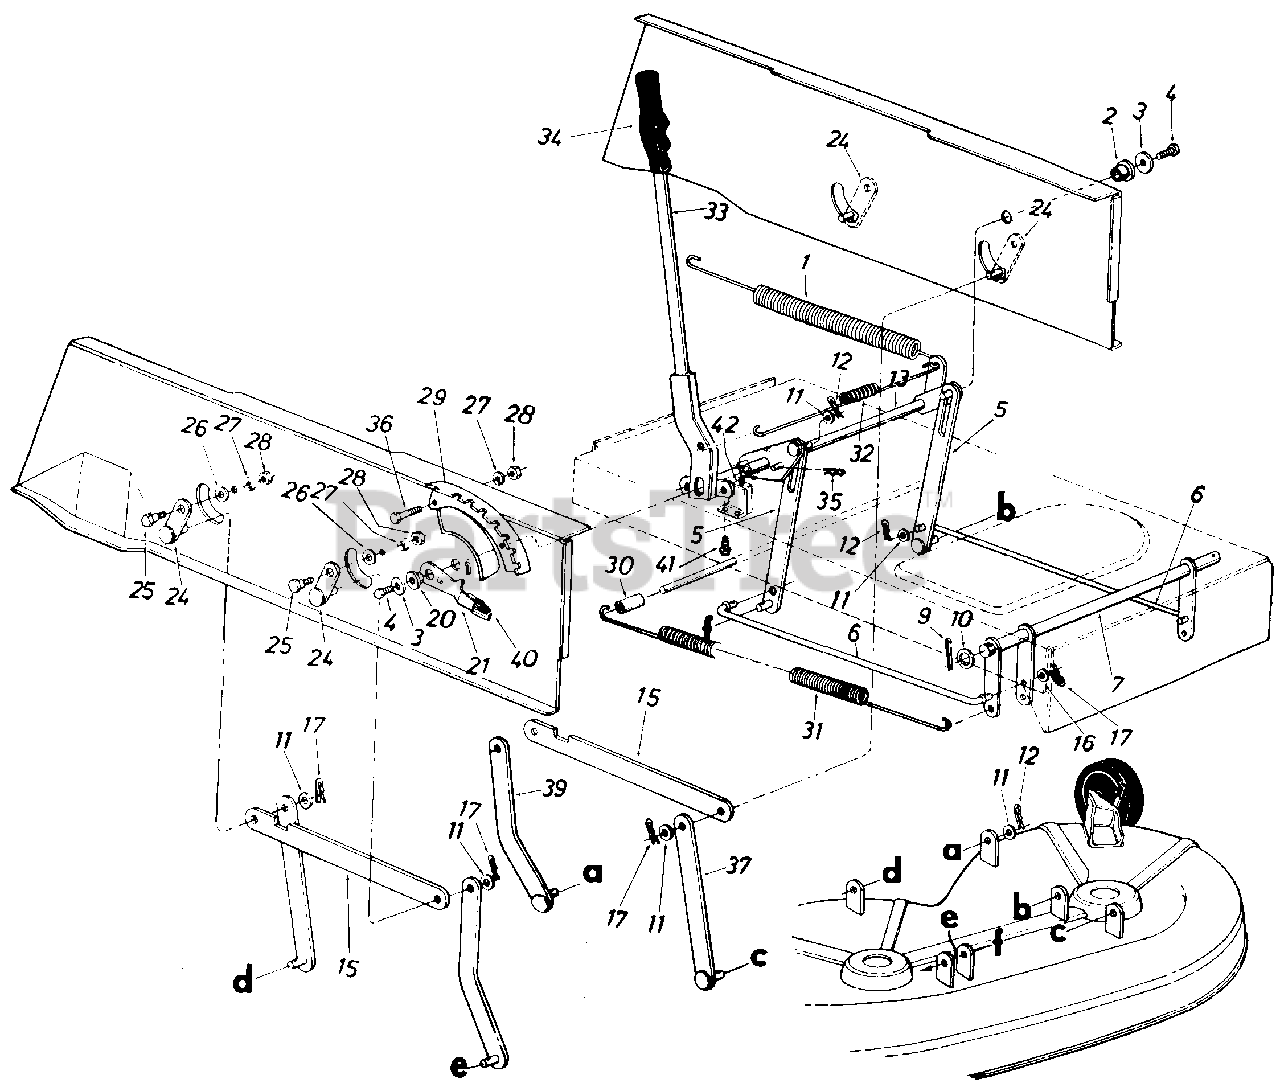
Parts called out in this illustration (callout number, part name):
1	Extension Spring .99" O.D. x 11.00" Lg.
2	Flange Bearing .634" I.D.
3	Fl-Wash. .344" I.D. x 1.125"
4	Hex Wash. Hd. 5/16-18 x .62" Lg.
5	Link Deck Lift Ass'y.
6	Stabilizer Rod
7	Stabilizer Shaft Ass'y.
9	Cotter Pin 1/8" Dia. x 1-1/4"*
10	Fl-Wash. .635" I.D. x 1.12"
11	Fl-Wash. .531" I.D. x .940"
12	Inter. Cotter Pin
13	Lift Shaft Ass'y.
15	Connecting Rod
16	Fl-Wash. .40" I.D. x .88"
17	Inter. Cotter Pin-3/8" Rod
20	Flange Brg. .630" I.D.
21	Deck Lift-Down Stop
24	Pivot Link Ass'y.
25	Shld. Bolt .437" Dia. x .180" Lg. (5/16-18)
26	Fl-Wash. .344" I.D. x .62"
27	L-Wash. 5/16" I.D.
28	Hex Nut 5/16-18 Thd.
29	Index Brkt.
30	Spacer .523" I.D. x .640" O.D. x 1.95" Lg.
31	Ext. Spring .99" O.D. x 1 3.25" Lg.
32	Ext. Spring .56" O.D. x 32 0 Coils
33	Lift Handle Ass'y.
34	Grip
35	Intern. Cotter Pin 1/2" Dia.
36	Hex Bolt 5/16-18 x .75"
41	Hex AB-Tap Scr. #10 x .50"
42	Safety Switch
